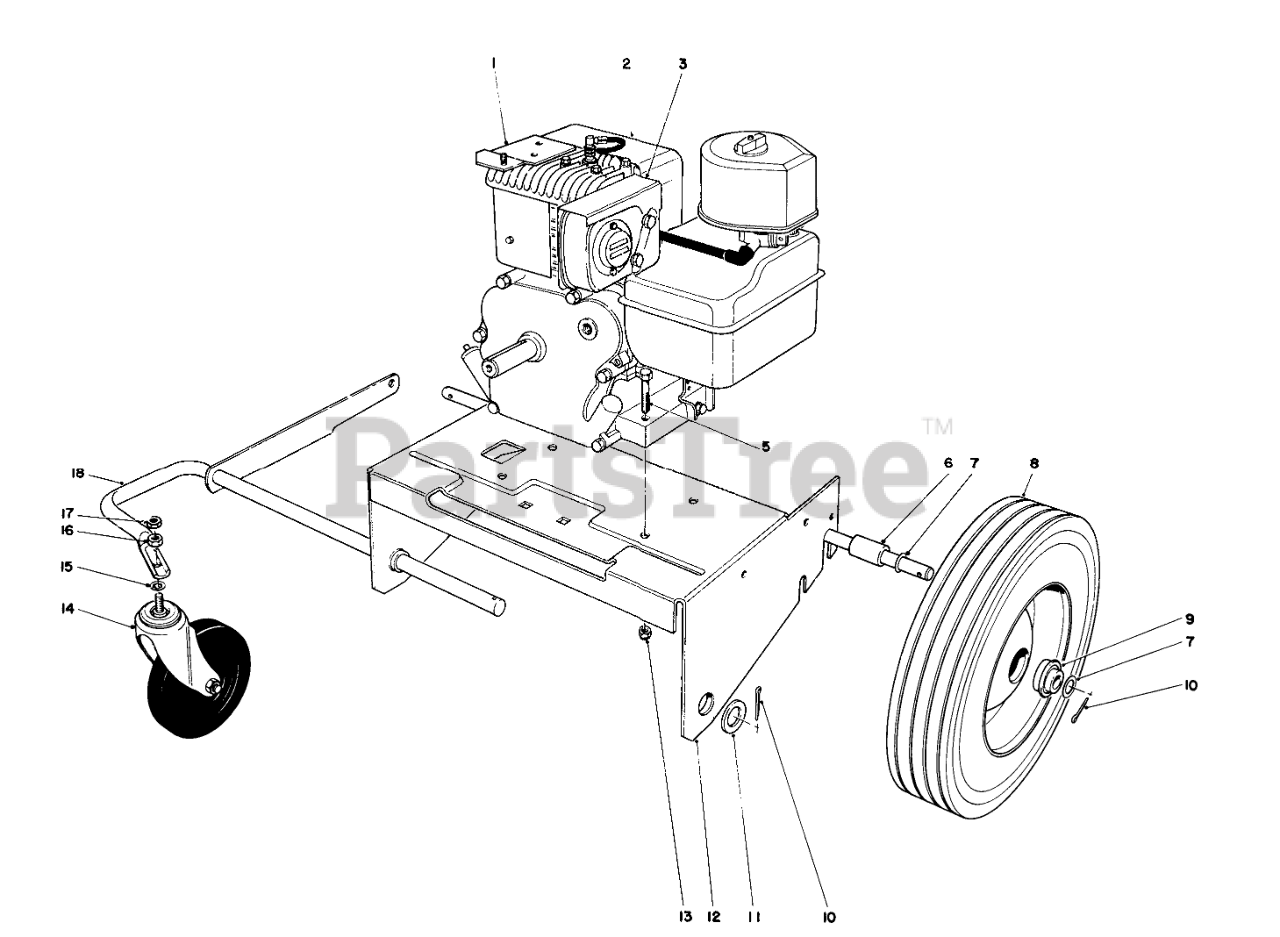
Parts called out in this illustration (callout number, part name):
1	MTG BRKT WA B
3	HEAT SHIELD
5	SCREW-HH
6	SPACER-AXLE
7	WASHER
8	Wheel (Incl. Ref. #9)
9	BEARING
10	PIN-COTTER
11	WASHER-FLAT
12	Engine Plate
13	NUT-LOCK, CONE
14	CASTER
15	WASHER-LOCK/INT
16	NUT-HH
17	1/2-13 CONELOCK NUT
18	Front Wheel Support
